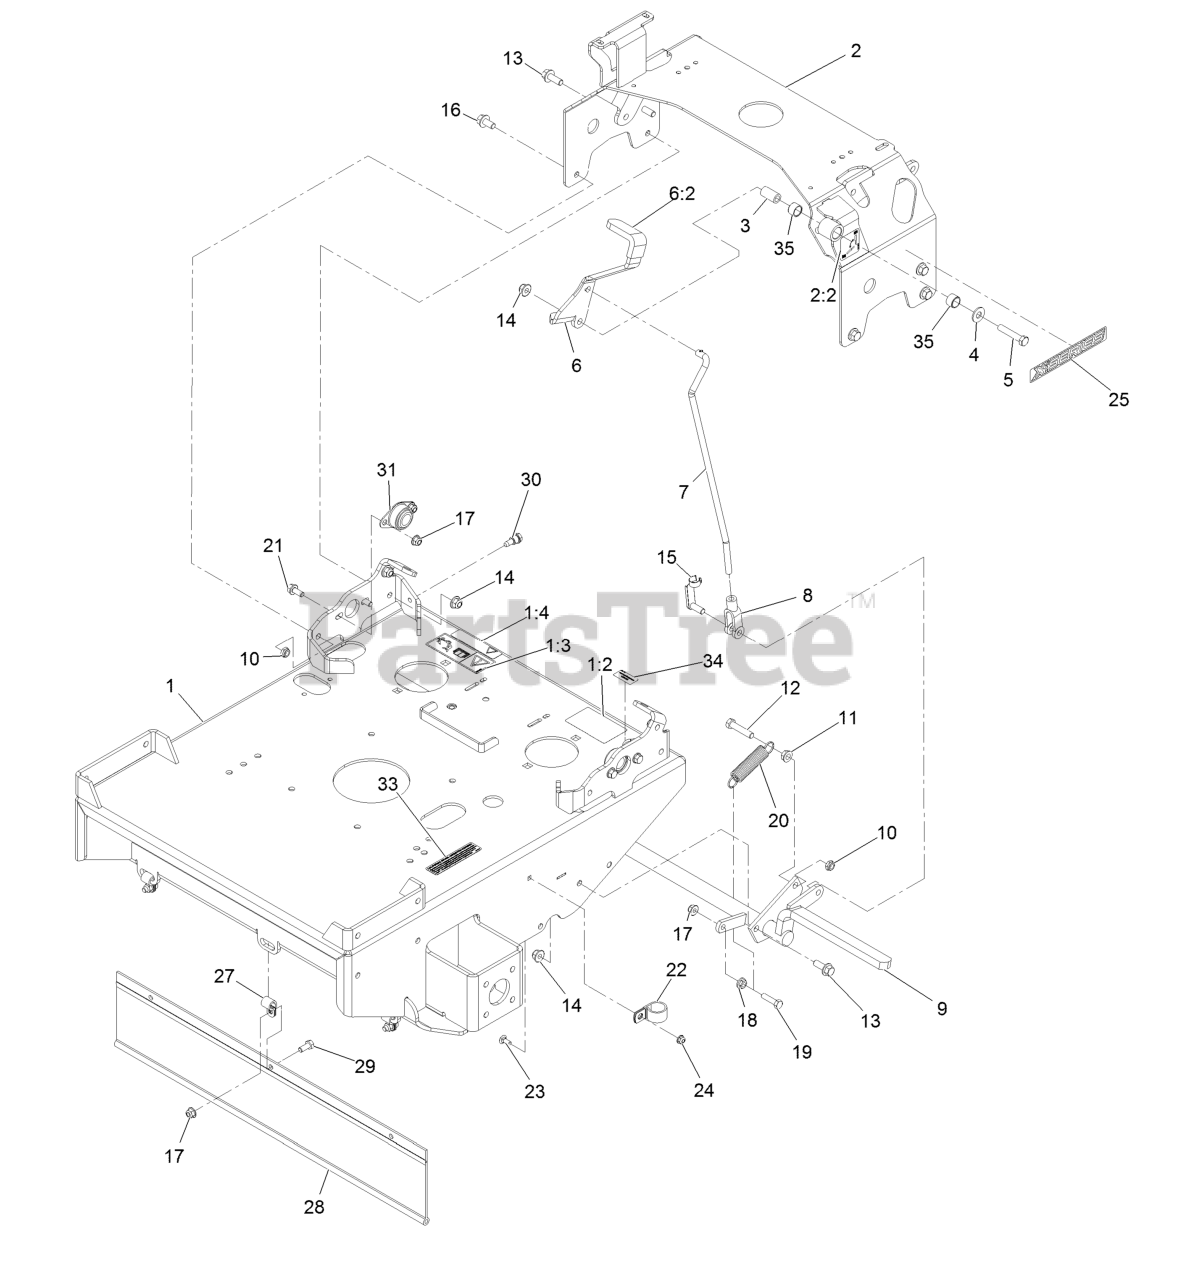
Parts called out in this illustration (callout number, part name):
1	ASM, Engine Deck W/Decals
1:2	Decal-Warning
1:3	Decal-Warning, Sulky
1:4	Decal-Drive Release
2	ASM, Tank Support W/Decal
2:2	Decal-Park Brake, CE
3	Bushing-Pivot
4	Washer-3/8 Std
5	Screw-HH 3/8-16 X 2
6	ASM, Brake Lever W/ Grip
6:2	Grip-Lever
7	Linkage-Brake
8	Yoke-Linkage, Brake
9	Wld,Brake Ttx
10	Nut-Nyloc 3/8-16 Thin
11	Nut-Whizlock 3/8-16
12	Screw-HH 3/8-16 X 1 3/4
13	Screw HHF 3/8-16 X 1
14	Nut-Nyloc 3/8-16 Flg
15	Pin-Clevis Spring 3/8
16	Screw-HH Flg 3/8-16 X 3/4
17	Nut-Nyloc 5/16-18 Flg
18	Nut-Whizlock 5/16-18
19	Screw-HH 5/16-18 X 1 1/4
21	Screw-HH Flg 5/16-18 X 3/4
22	Clip-Loom
23	Bolt-Carriage 1/4-20 X 5/8
24	Nut-Nyloc 1/4-20 Flg
25	Decal-X-Series
27	Clip-Loom
28	Shield, Drag
29	Screw-HH 5/16-18 X 3/4
30	Bolt-Shoulder
31	Bearing-Flanged
33	Decal-Arrester, Spark
34	Decal-Patent
35	Sleeve-Bushing
